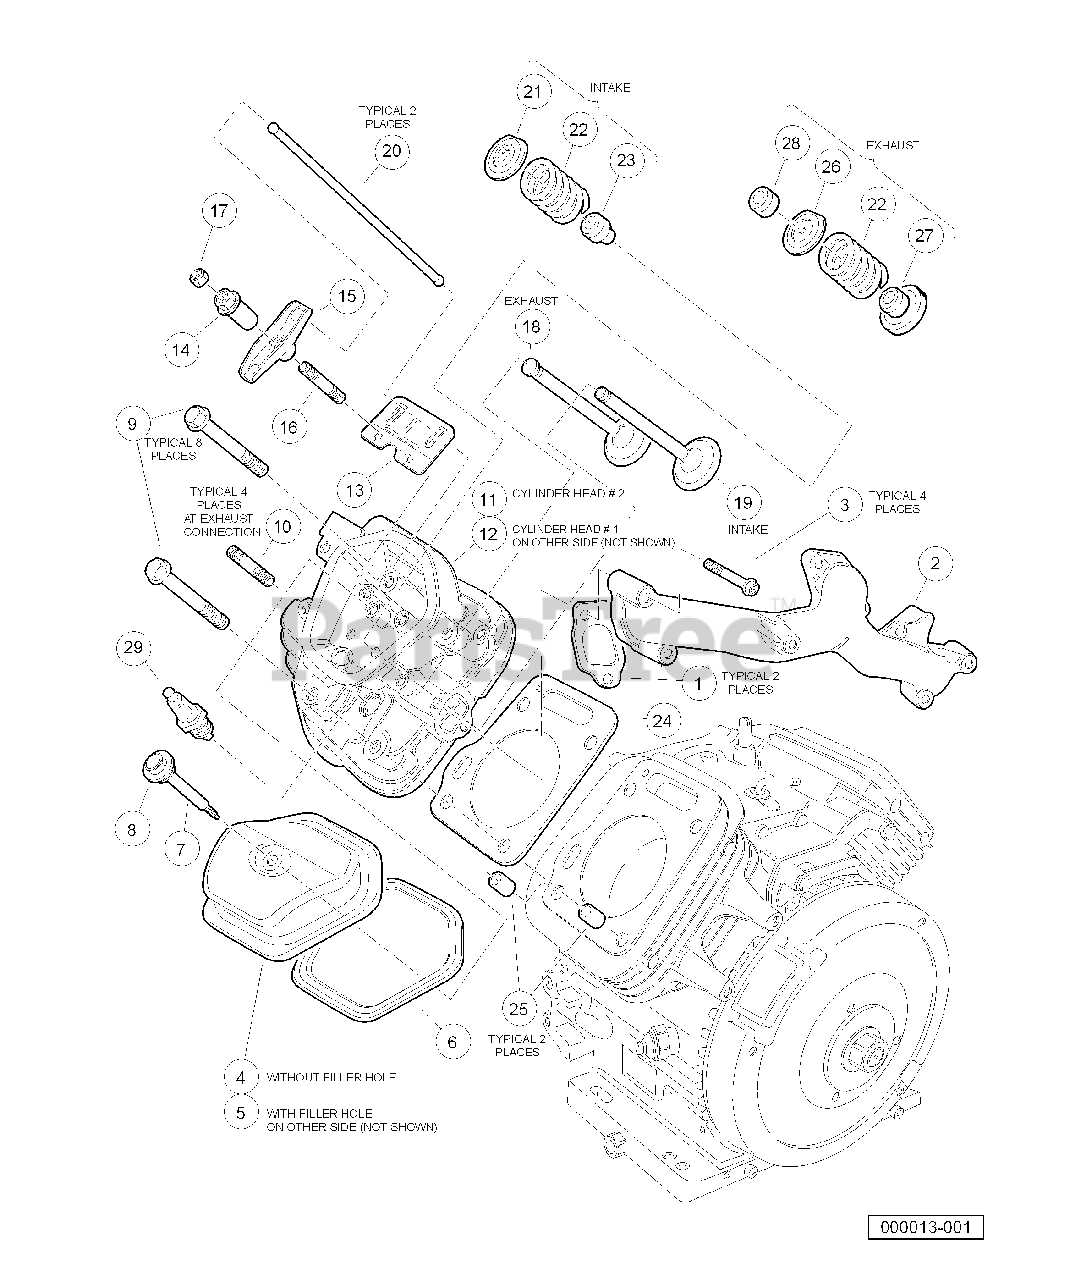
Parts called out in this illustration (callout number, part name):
1	Gasket, Intake Manifold
2	Manifold, Inlet
3	Bolt, Socket, M8 X 1.25 X 45
4	Cover, Head
5	Cover, Head Filler
6	Gasket, Cylinder Head Cover
7	Bolt, Head Cover
8	Washer, Head Cover
9	Bolt, Flange Head, M10 X 1.5 X 80
10	Bolt, Stud, M8x22
11	Cylinder Head, #2
12	Cylinder Head, #1
13	Plate, Push Rod Guide
14	Pivot, Rocker Arm
15	Arm, Valve Rocker
16	Bolt, Pivot, M8
17	Nut, Pivot Adj
21	Retainer, In Valve Spring
22	Spring, Valve
23	Seal, Valve Stem
24	Gasket, Cylinder Head
25	Pin A, Dowel ,12 X 20
26	Retainer, Ex Valve Spring
27	Seat, Valve Spring
28	Rotator, Valve
29	Spark Plug, BPR2ES
